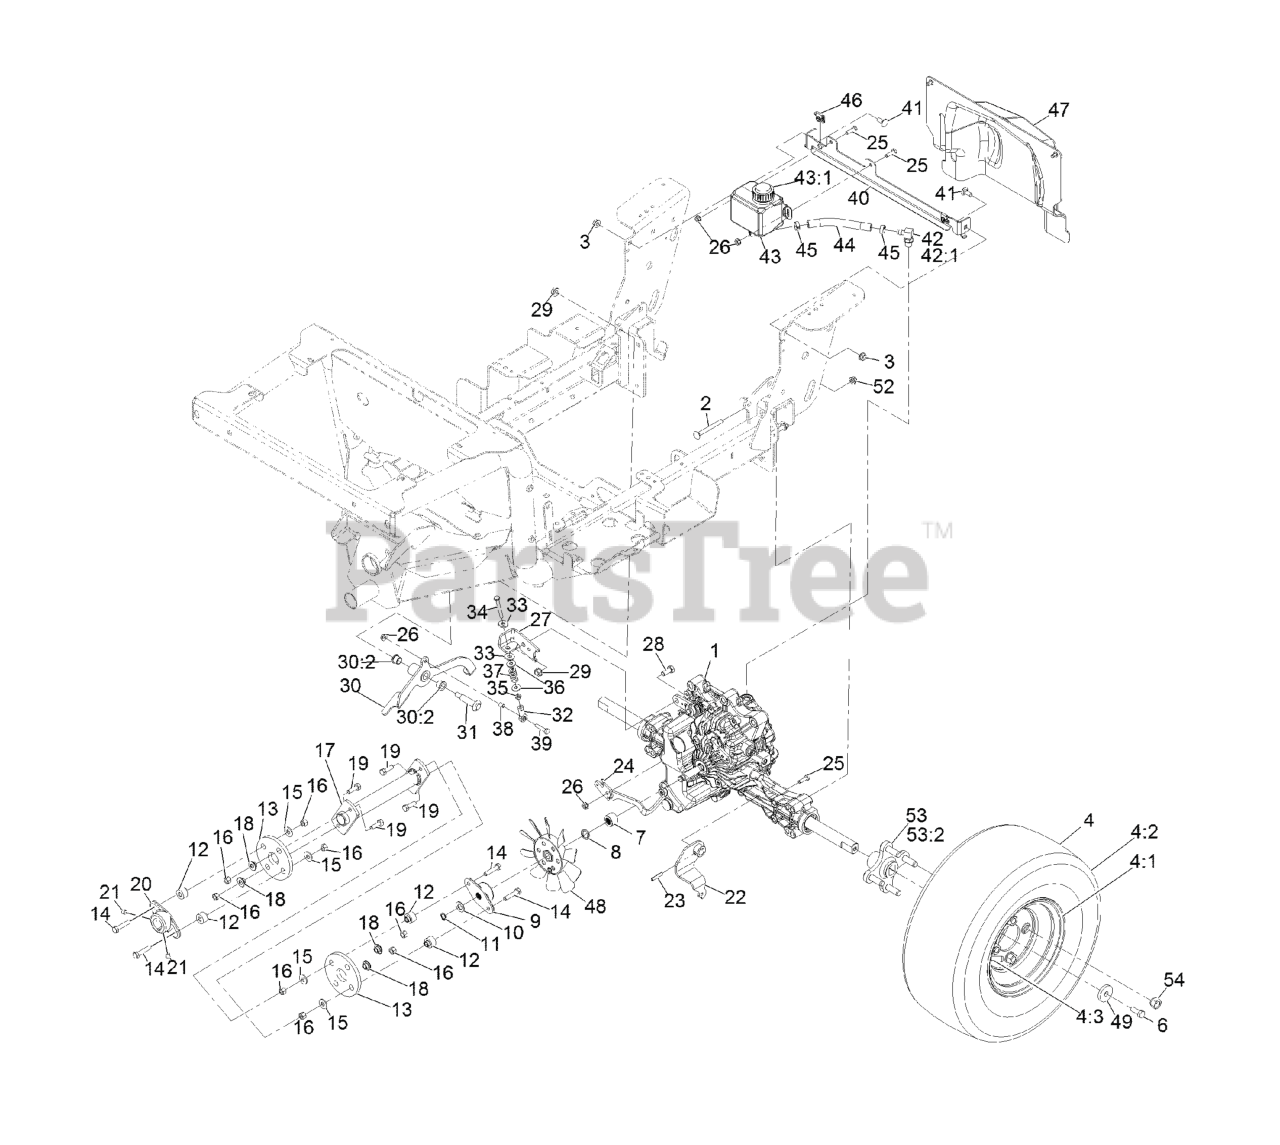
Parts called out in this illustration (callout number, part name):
1	TRANSAXLE
2	SCREW-CARR
4	WHEEL AND TIRE ASM(18X7.5
4:1	TIRE-4 PLY
4:2	Wheel, 8 X 5.375
4:3	Stem-Valve
6	SCREW-HH
7	SPACER-SHAFT, INPUT
8	WASHER-SPRING
9	HUB-SHAFT, TRANSAXLE
10	SPACER
11	RING-RETAINING
12	SPACER-COUPLING, RUBBER
13	COUPLING-RUBBER
14	SCREW-HH
15	WASHER-FLAT
16	NUT-HEX
17	Drive Shaft ASM, Welded
18	SPACER-COUPLER, RUBBER
19	SCREW-HH
20	HUB-SHAFT, ENGINE
21	SETSCREW
22	ARM-MOTION
23	PIN-SPIRAL
24	ARM-RELEASE
25	SCREW-HH
27	ARM-BRAKE
28	SCREW-HH
30	BRAKE LEVER ASM
30:2	BEARING-FLANGE
31	BOLT-SHOULDER
32	ROD END-BALL JOINT
33	WASHER-SPRING
34	SCREW-HH
35	NUT-JAM
36	WASHER-FLAT
37	SPRING-COMPRESSION
38	SPACER
39	SCREW-HH
40	BRACKET-MOUNT, TANK
41	SCREW-CARR
42	FITTING-90 DEG
42:1	O-RING
43	TANK ASM
43:1	CAP-TANK
44	HOSE-EXPANSION
46	RECEPTACLE-CLIP, MINI
47	TRANSAXLE COVER ASM
48	FAN-7 INCH
49	WASHER-CLUTCH
52	NUT-HF, NI
53	WHEEL HUB ASM
53:2	STUD-TYPE, DRIVE
54	NUT-LUG
